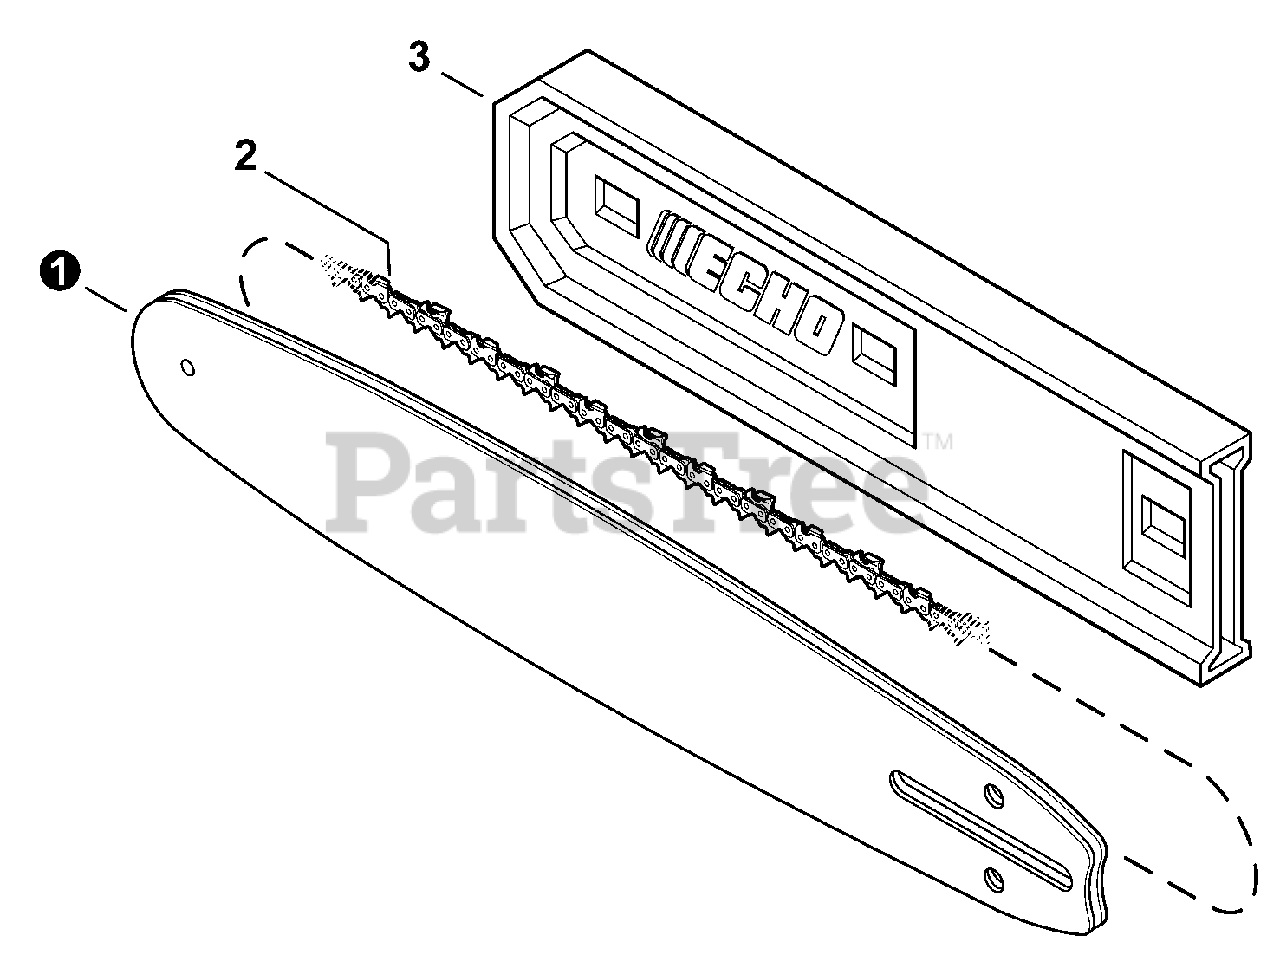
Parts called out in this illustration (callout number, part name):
1	GUIDE BAR, 12" 0.043" GA
1	GUIDE BAR, 12" 0.050" GA
2	SAW CHAIN 12" 0.043" GA
2	SAW CHAIN 12" 0.050" GA
3	SCABBARD 12"
